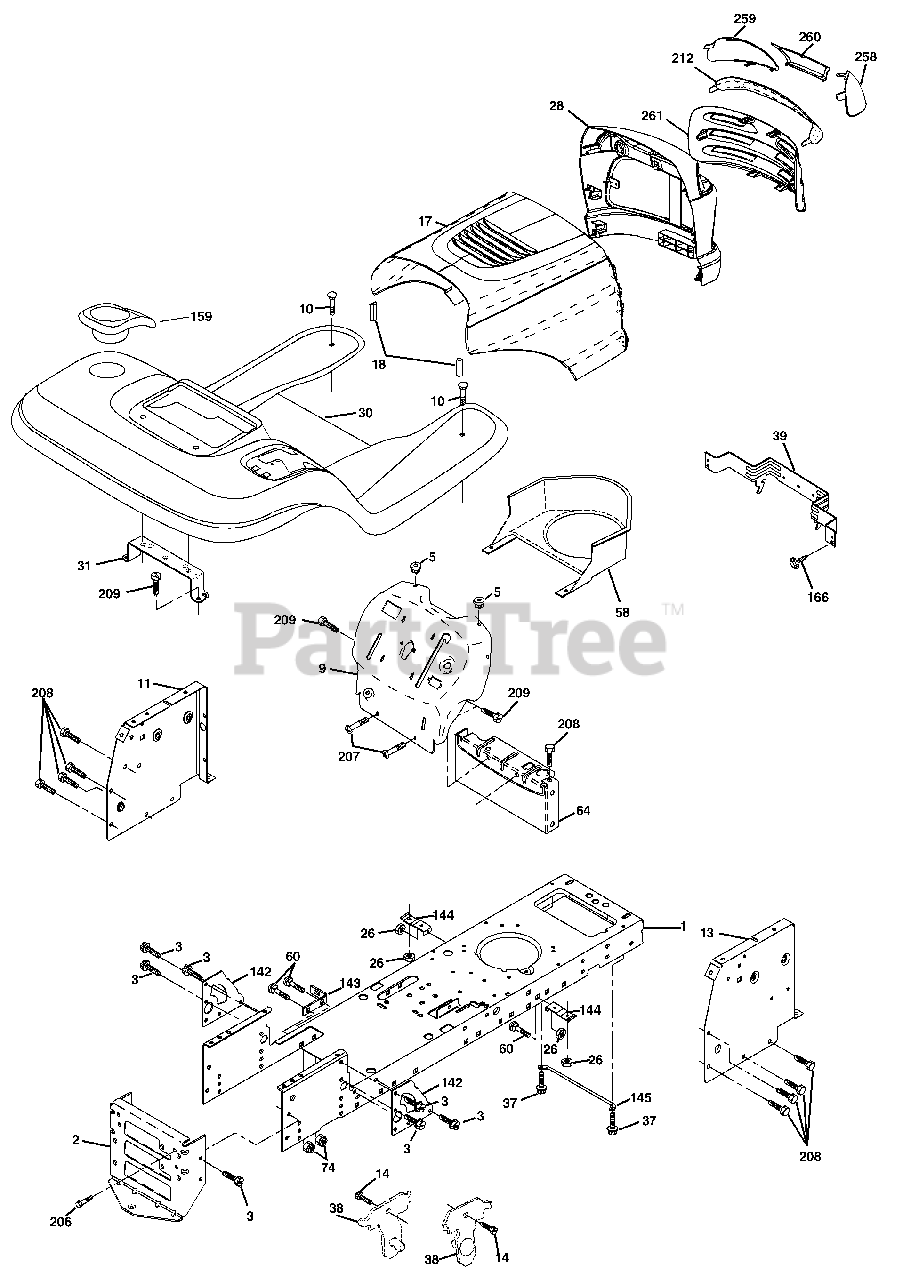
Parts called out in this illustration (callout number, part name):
1	Chassis Stamping
2	Drawbar, 12 Ga.
3	Screw 3/8-16 x 3/4
5	Bumper Hood/Dash
9	Dash Slkscr
10	Bolt Carriage 3/8-16 x 1
11	Panel Dash Lh
13	Panel Dash Rh
14	Screw Thdrol 3/8-16 x 1/2
17	Hood LT/PL
18	Bumper Hood
26	Nut Lock Hex W/Ins 3/8-16 Unc
28	Grille/Lens Asm
30	Fender Footrest
31	Bracket Fender
37	Screw Thdrol 6/16-18 x 1/2 TYT
38	Bracket Asm Pivot Mower Rear
39	Bracket Pivot
58	Air Duct Engine P/L
60	Bolt Rd Hd Sqnk 3/8-16 Unc x 3/4
64	Dash Lower STLT
74	Nut Crownlock 3/8-16 Unc
142	Plate Reinforcement STLT
143	Bracket Swaybar Chassis
144	Bracket Footrest
145	Rod Pivot Chassis/Hood
159	Cupholder
166	Screw Hw Hd Hi-Lo #13-16 x 3/4
206	Bolt Shoulder 5/16-18 TT
207	Screw Thdrol 5/16-18 x 1/2
208	Screw Thdrol 3/8-16x1/2 Ty-tt
209	Screw Hex Wsh Thdr. 3/8-16 x 3/4
212	Insert Lens Reflective
258	Lens Husq Laser LT Clear RH
259	Lens Husq Laser LT Clear LH
260	Cover Lens
261	Insert Grille
